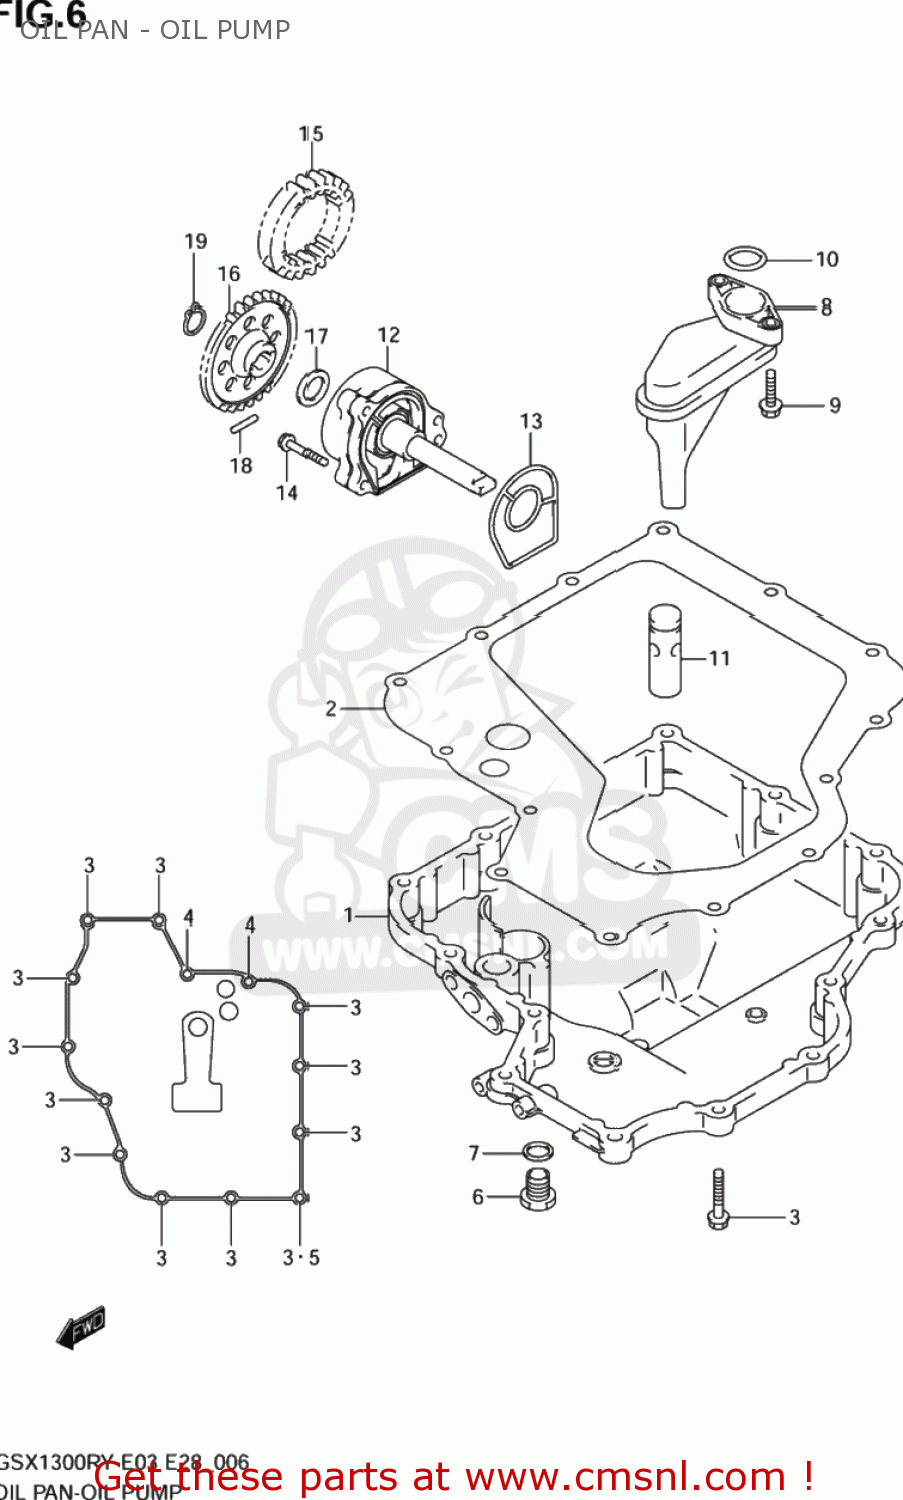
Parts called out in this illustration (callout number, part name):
1	PAN,OIL
2	GASKET,OIL PAN (NAS)
3	BOLT,G/S SWITC
4	BOLT
5	GASKET(5.8X13X1.2) (NAS)
6	PLUG(14X20)
7	GASKET(13.8X18.8X4.8) (NAS)
8	STRAINER,ENGINE OIL
9	BOLT
10	O RING(D:2.62,ID:20.3)
11	VALVE ASSY,OIL RELIEF(7K)
12	PUMP ASSY,ENGINE OIL
13	O RING,OIL PUMP
14	BOLT,G/S SWITC
15	GEAR,OIL PUMP DRIVE
16	GEAR,OIL PUMP DRIVEN
17	SHIM(12X20X0.5)
18	PIN(5X18)
19	CIRCLIP,12 MM
